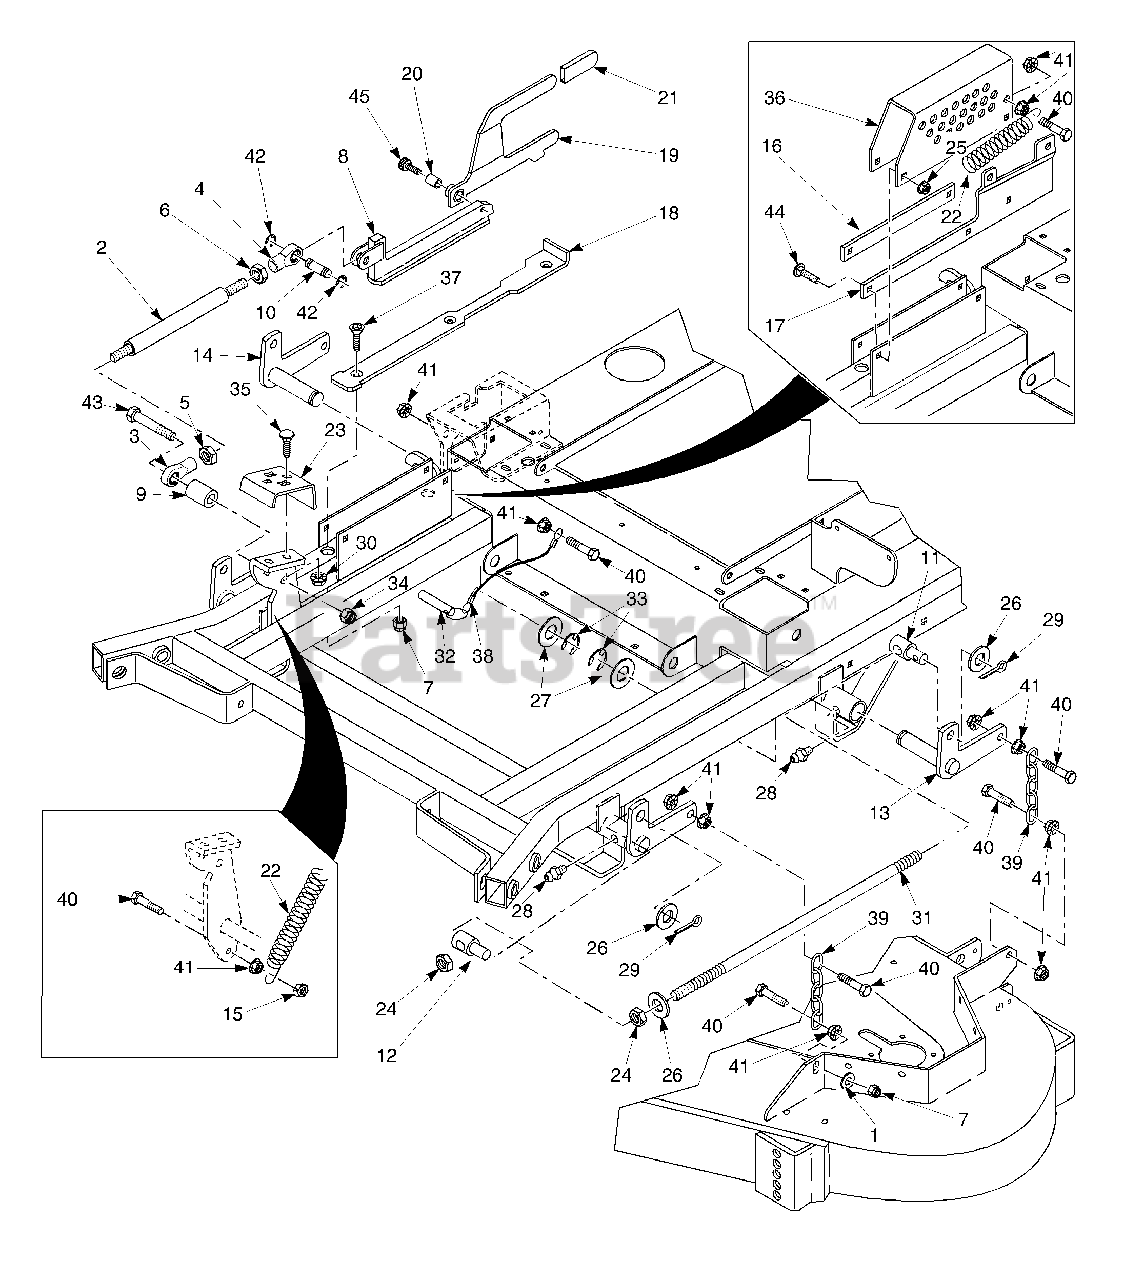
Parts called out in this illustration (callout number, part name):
1	Flatwasher, 3/8"
2	Link, Deck Lift
3	Rod End, Female - 1/2-20 RH
4	Rod End, Female - 1/2-20 LH
5	Nut, Jam 1/2-20 RH
6	Nut, Jam 1/2-20 LH
7	Nut, 3/8-16 Elastic Stop
8	Slide Weldment, Height Adjustment
9	Spacer, Decklift Pedal
10	Pin, Decklift
11	Swivel Joint, LH
12	Swivel Joint, RH
13	Bellcrank Weldment, LH Rear
14	Bellcrank Weldment, RH Rear
15	Locknut, 3/8-16 Center Lock
16	Guide, Short
17	Guide, Long
18	Lockplate, Decklift
19	Deck Latch
20	Bushing, .502 ID.
21	Grip, Deck Latch
22	Spring, Helper (61" & 72" Cutter Decks Only)
23	Foot Pedal, Height Adjustment
24	Nut, Hex 5/8-11
25	Nut, Hex Serrated Flange 5/16-18
26	Flatwasher, 5/8" (.656 x 1.312 x .095)
27	Flatwasher, 1" (1.062 x 1.50 x .048)
28	Grease Fitting
29	Cotter Pin, 3/16 x 1"
30	Nut, Hex Elastic Stop 5/16-18
31	Stud, 5/8-11 x 22.0"
32	Ring Pin, 1/2 x 3.06"
33	Ring, Retaining 1" External "E"
34	Nut, Hex Elastic Stop 1/2-13
35	Bolt, Carriage 3/8-16 x 1-1/4"
36	Bracket, Cutting Height Adjustment
37	Screw, Cap 5/16-18 x 3" FHHS
38	Lanyard, Deck Height Pin
39	Chain
40	Bolt, Hex Head 3/8-16 x 1-1/2"
41	Nut, Hex Serrated Flange 3/8-16
42	Ring, Retaining 1/2" External "E"
43	Bolt, Hex Head 1/2-13 x 3"
44	Bolt, Carriage 5/16-18 x 1"
45	Bolt, Shoulder 1/2 x 3/4"
